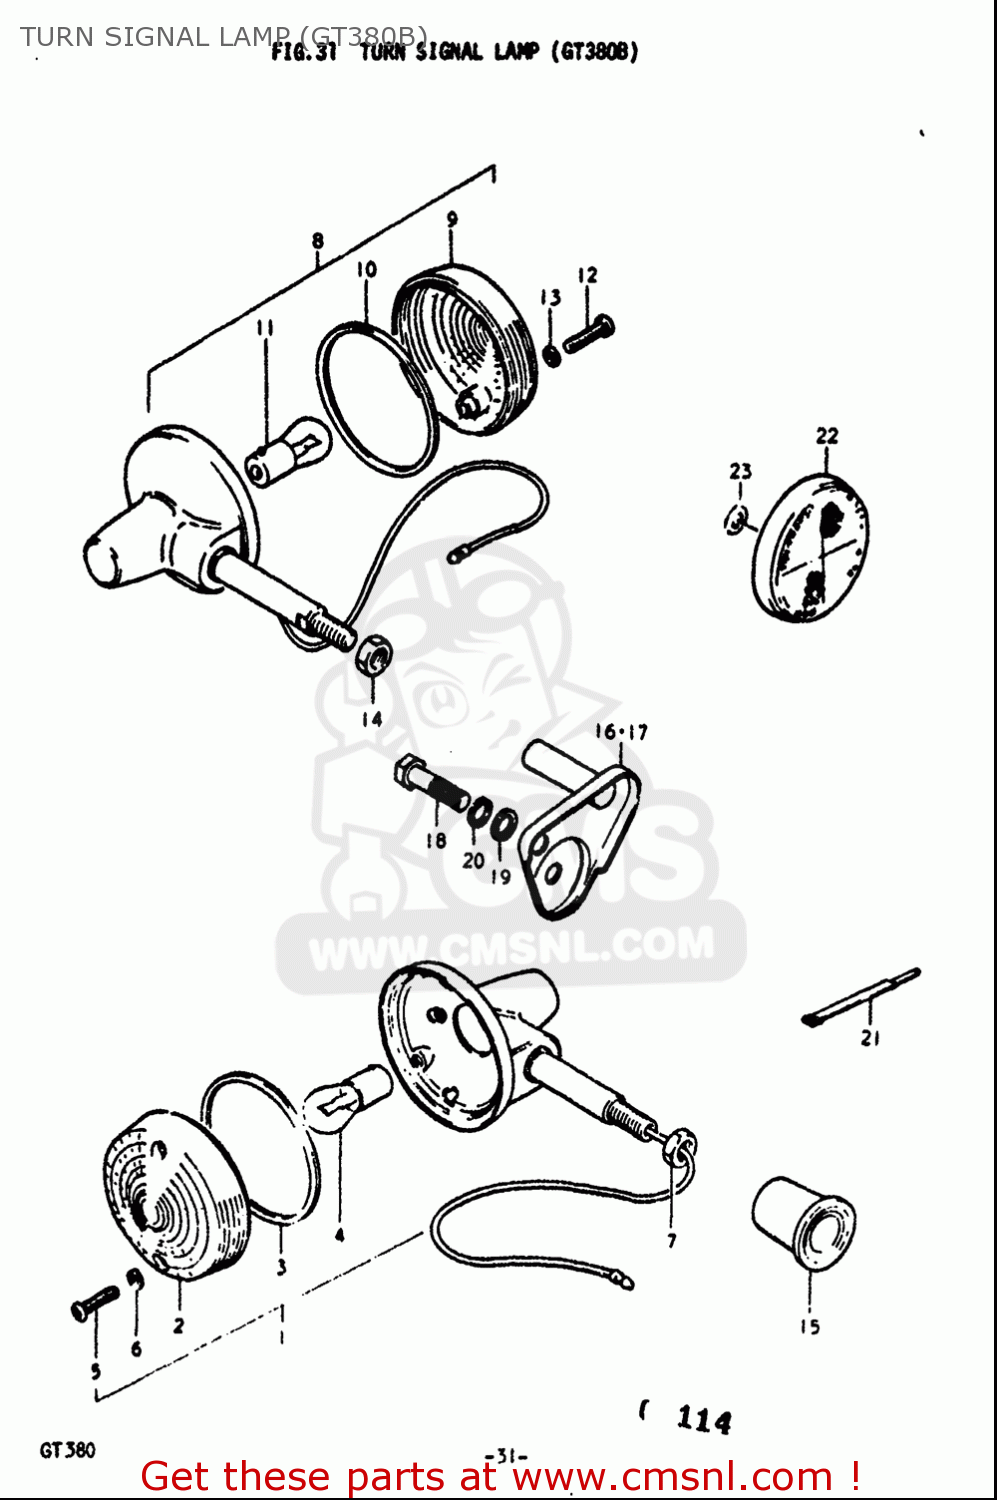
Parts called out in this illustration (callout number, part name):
2	LENS
3	GASKET (NAS)
4	BULB(12V23W,STANLEY,A4577A)
6	GASKET (NAS)
7	NUT
8	LAMP ASSY,RR TURNSIGNAL
9	LENS
10	GASKET (NAS)
11	BULB(12V23W,STANLEY,A4577A)
13	GASKET (NAS)
14	NUT
15	COVER,FRONT TURN SIGNAL BRACKET
16	BRACKET, REAR TURN SIGNAL RH
18	BOLT
19	WASHER
20	WASHER,LOCK
21	CLAMP
22	REFLEX REFLECTOR,FR
23	WASHER
